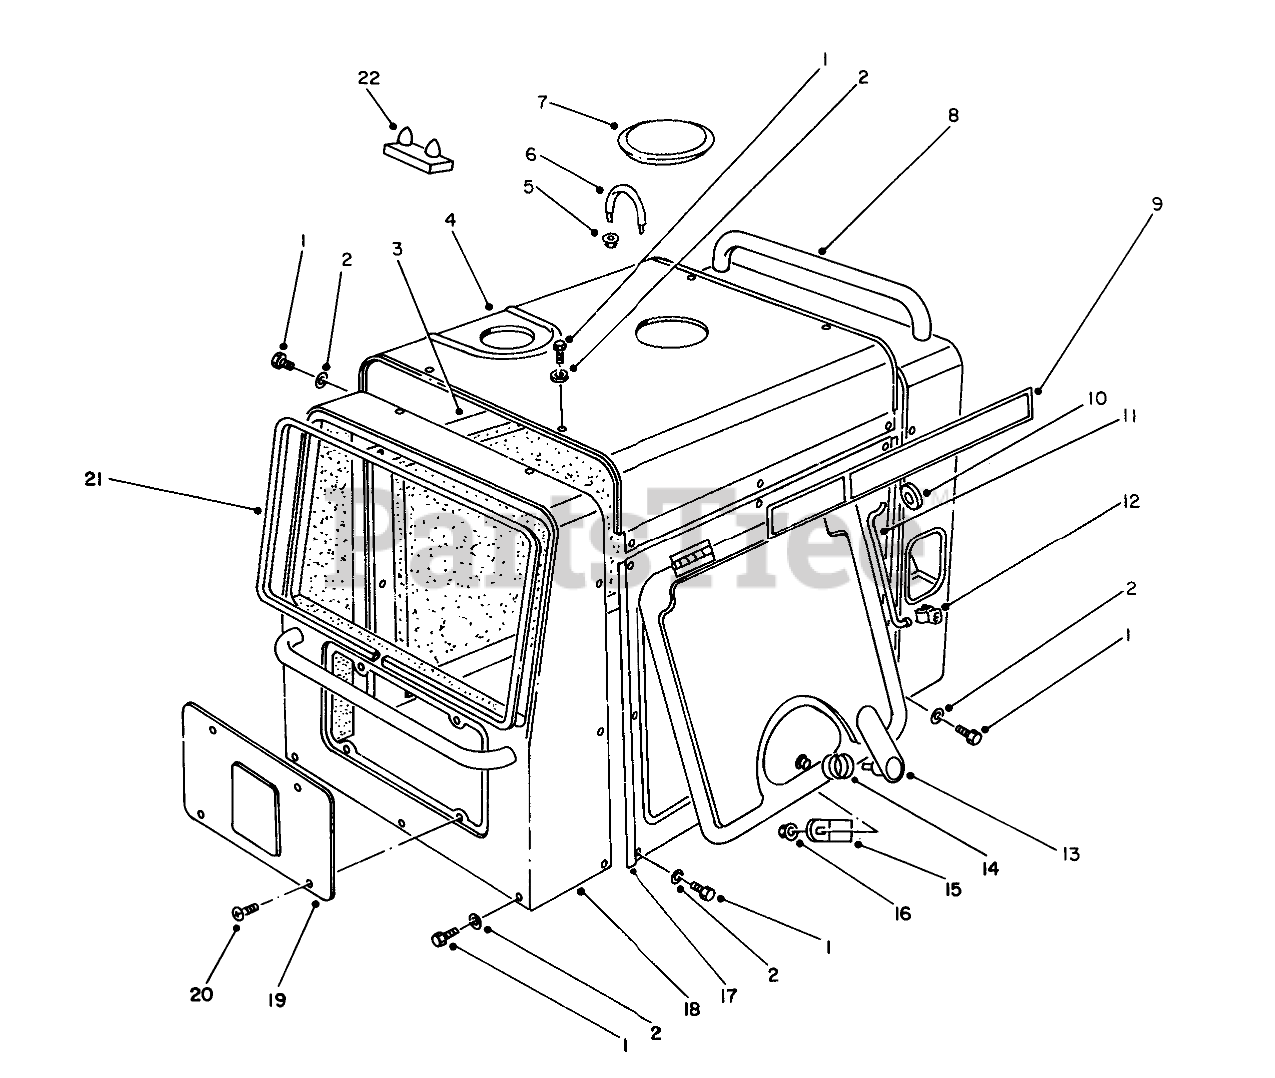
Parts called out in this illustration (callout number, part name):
2	Washer
3	Cover L.H.
4	Cover-Upper
6	U-Bolt
8	Cover-Rear
9	Decal-Toro
10	Grommet
11	Rod-Door Stop
12	Clamp
13	Handle-Door
14	Spring
15	Plate-Handle
17	Cover R.H.
18	Cover-Front
19	Lid-Terminal
20	Screw
21	Seal-Front Cover
22	Cushion
